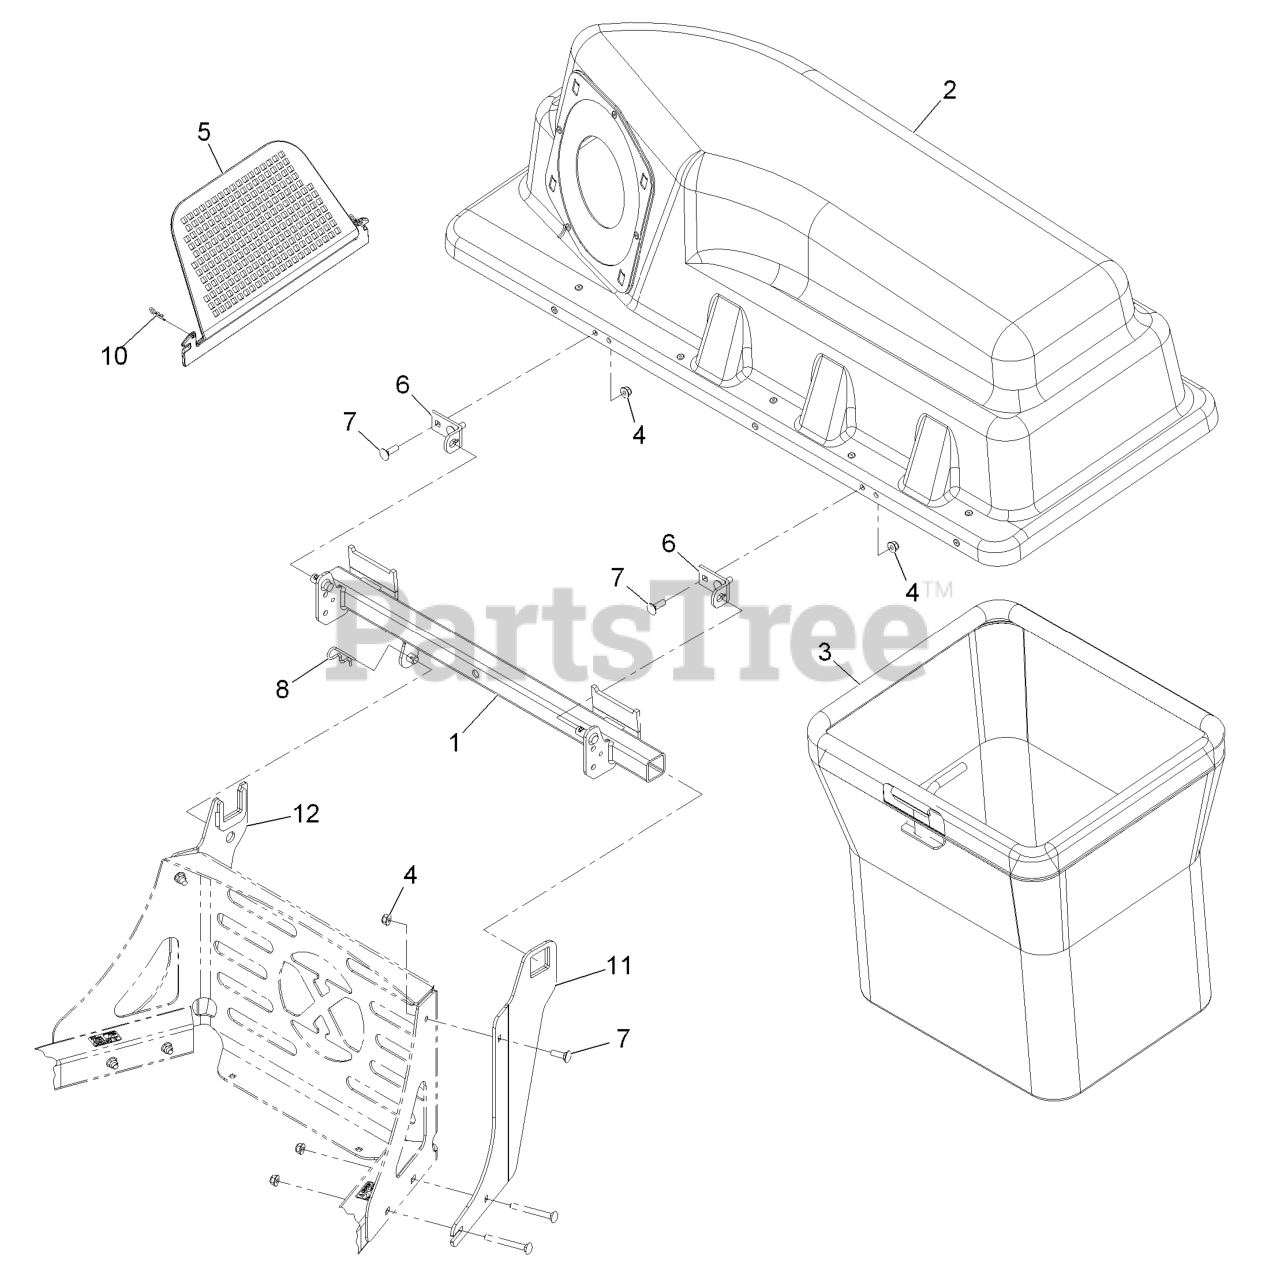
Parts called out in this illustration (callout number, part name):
1	FRAME PIVOT ASM
2	BAGGER HOOD ASM
3	ASM,BAG
4	NUT-HF, NI
5	SCREEN-BAGGER
6	BRACKET-PIVOT, HOPPER
7	BOLT-CARR
8	PIN-HAIR
11	BRACKET ASM, LH
12	BRACKET ASM, RH
